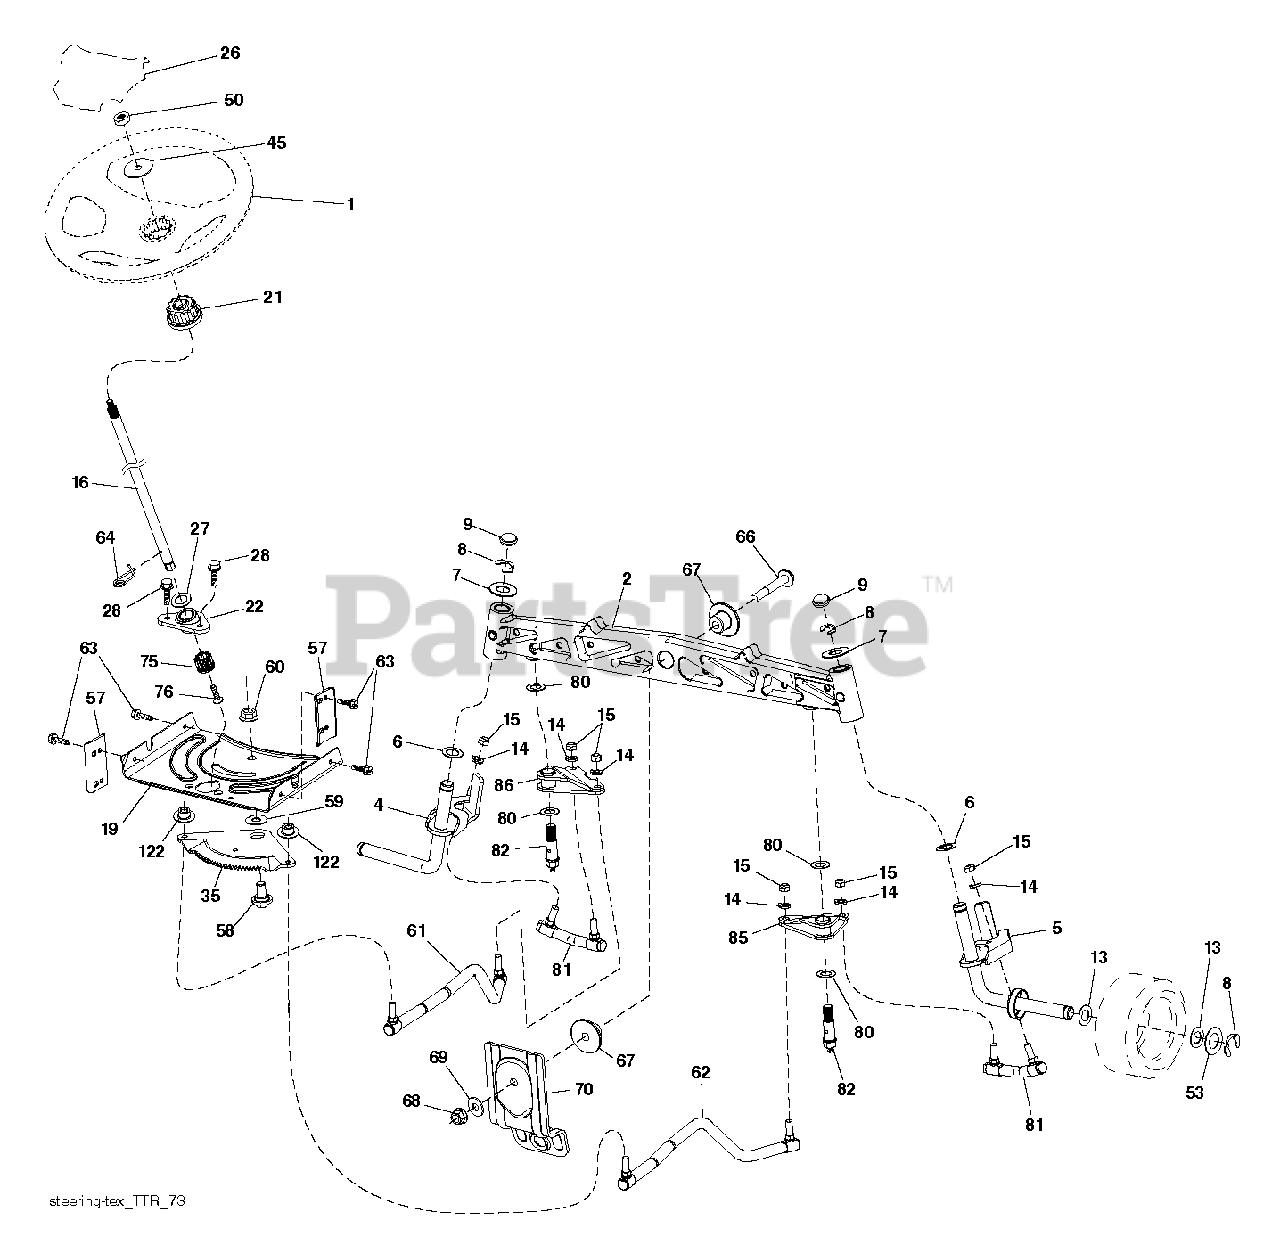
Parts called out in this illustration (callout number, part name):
1	WHEEL.STEERING.HUSQ.PREM.HRDRM
2	AXLE.CAST.IRON
4	SPINDLE.WELDED.LH.15"TEX
5	SPINDLE.WELDED.RH.15"T
6	THRUST WASHER
9	CAP.SPINDLE.BLACK
14	WASHER, LOCK 3/8
15	NUT CROWNLOCK 3/8-24
16	SHAFT.STEER.2HIGH.SPLND.PLATED
19	PLATE.STEER.DDL.NLT/NG
21	ADAPTER.WHEEL.STEER.SPLND.ALUM
22	BEARING.SHAFT.STEER.LOWER.625
26	INSERT.CAP.WHL.STRG.HUSQ.PREM
28	SCREW, 3/8-16X3/4
35	GEAR.SECTOR.PLATE.DDL.
45	WASHER.3/8ID.2-3/8OD.12GA.PLTD
50	NUT LOCK FLG 3/8-16 UNC
53	WASHER.HARDENED
57	BRACKET.UPSTOP.TEX
58	BOLT.SHOULDER.SECTOR.P
59	WASHER.THURST.SECTOR.S
60	NUT FLANGE LOCK 5/8-11
61	LINK SUBASM.LINK.DRAG.LH.NZTR
62	TUBE TUBE
63	SCREW
64	RETAINER.CLIP.SPRING.S
66	BOLT HEX FGHD 7/16-14 X 3 SERR
67	BUSHING.PM.FRONT AXLE
68	NUT.LOCK.FLANGE.7/16
69	WASHER.1.5X.505X.118
70	BRKT.DECK.SUSPENSION.F
75	PINION.ZINC PLATED
76	SCREW HEAD SOCKET LRVB
80	THRUST WASHER
81	LINK SUBASM.LINK.CROSS.NZTR
82	SUBASM;PIVOT;BOLT;NZTR
85	PIVOT SUBASM.PIVOT.RH.NZTR
86	PIVOT SUBASM.PIVOT.LH.NZTR
122	CAP.GEAR.SECTOR.TEX
